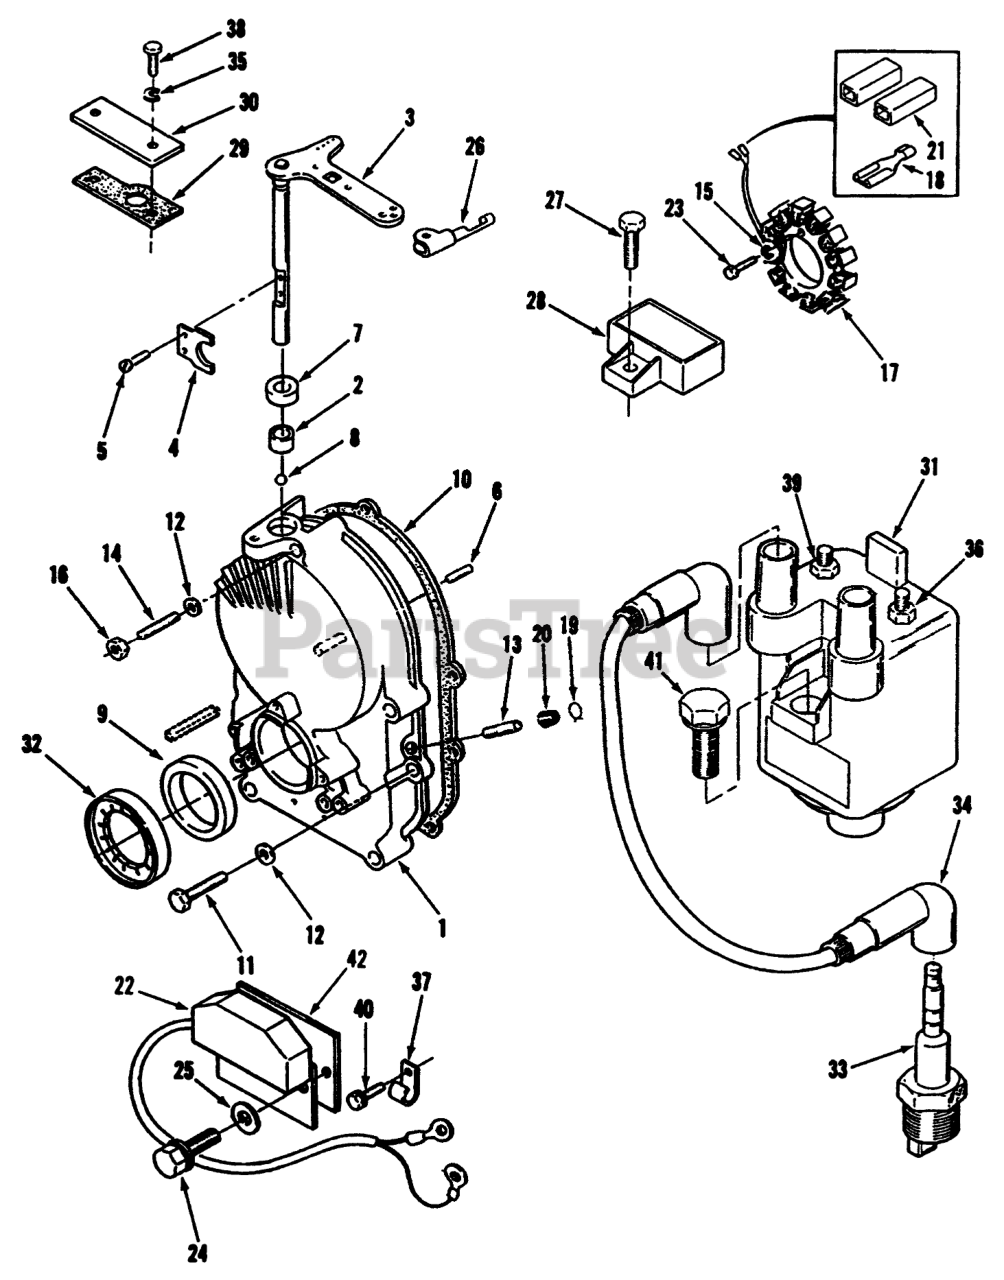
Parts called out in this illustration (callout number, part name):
1	Kit-Gearcase (Incl. Ref. #2-9,13,19, & 20)
2	BEARING
3	SHAFT AND ARM
5	SCREW-PAN HD
6	Washer
8	Bearing
10	GEAR CASE MTG GASKET
11	Bolt
12	WASHER
13	TUBE-PORT, VACUUM
14	Stud
15	WASHER-LOCK, SPRING
16	Nut
17	Stator w/Terminals
18	Stator Leads Terminal
19	CLAMP
20	CAP-FUEL OUTLET
21	BODY-TERM. CONNECTOR KIT
22	Control-Ignition
23	Screw-HH
24	Bolt
25	WASHER-LOCK
27	Bolt
28	Regulator
29	Gasket-Plate
30	Plate
31	Coil-Ignition
32	Rotor
33	SPARK PLUG
34	WASHER-FLAT
35	WASHER-FLAT
36	Nut
37	Clip
38	SCREW - CAP HEX HEAD
39	Nut
40	Bolt
41	Bolt
42	Insulator
